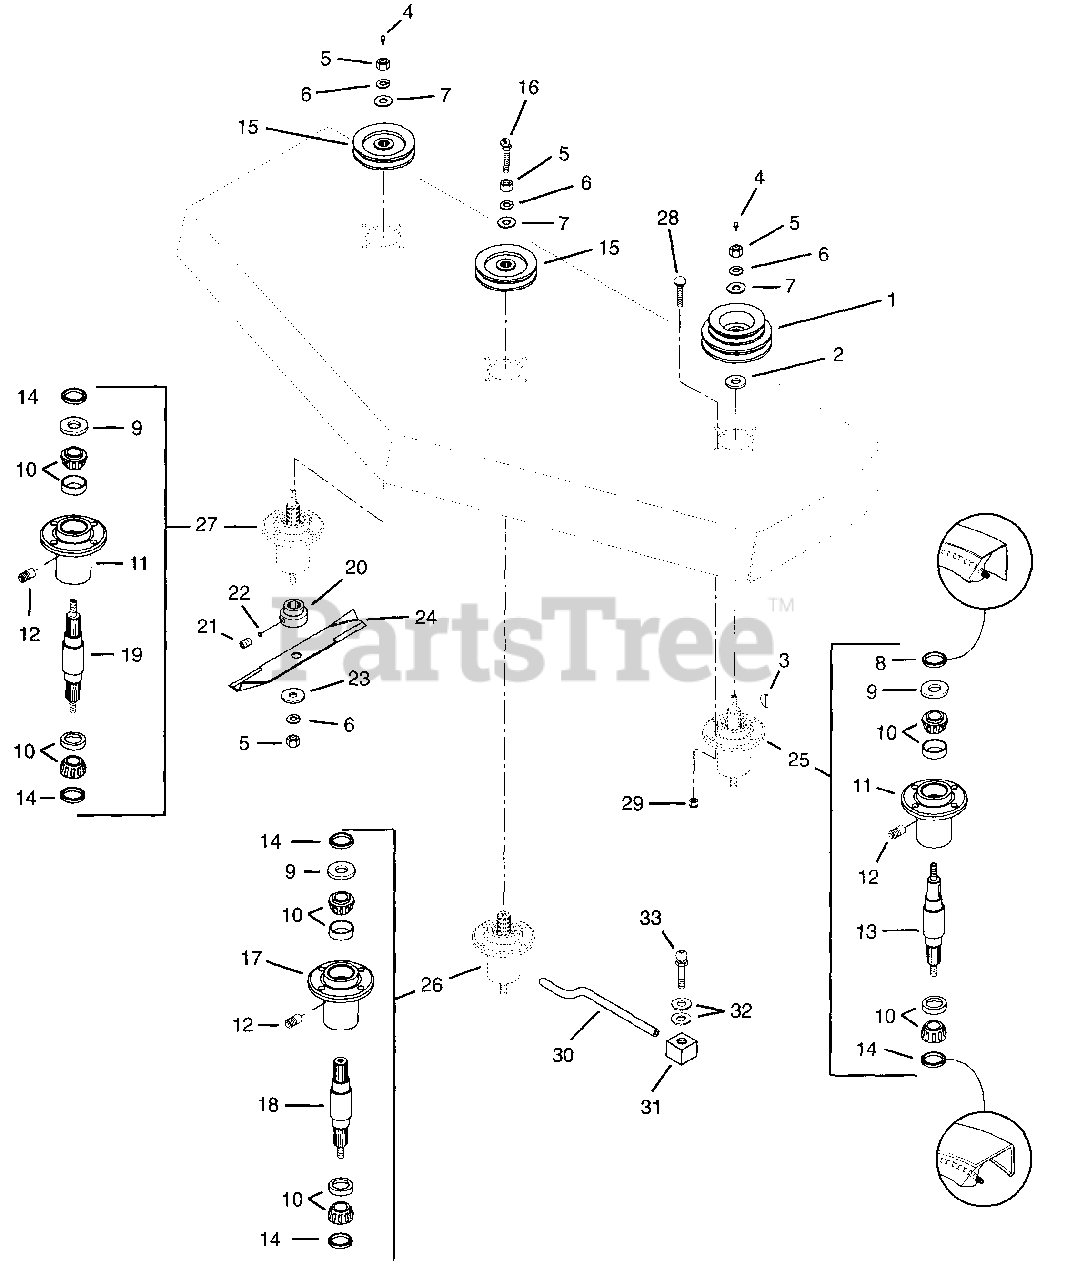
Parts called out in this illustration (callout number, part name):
2	Washer-Hardened-Thrust 1.00 x 1.55 x .03
3	Key-Woodruff .25 x 1.00 Hard #15
4	Fitting-Lube 1/8
5	Nut-Hex .625-11 Grade 2
6	Washer-Lock .625 x .156
7	Washer-Flat-Steel .687 x 1.312 x .150
8	Seal 1.987 x 1.500 x .313
9	Washer-Flat Steel 1.007 x 1.542 x .062
10	Assembly-Bearing Cup & Cone
11	Bearing Housing
12	Relief Fitting-Grease
13	Spindle Shaft Service Assembly
14	Seal 1.987 x 1.375 x .313
16	Bolt-Hex Spec 1/2-13 x 1.34
17	Bearing Housing
18	Spindle Shaft
19	Spindle Shaft Service Assembly
21	Screw-Set .25-20 x .25
23	Washer
24	Blade
25	Spindle Service Kit (Left)
26	Spindle Service Kit (Center)
27	Spindle Service Kit (Right)
28	Bolt-Round Head Square Neck .38-16 x 1.375
29	Nut-Locking-Nylon .375-16 Grade 2
30	Grease Tube
31	Grease Fitting
32	Washer-Flat-Steel .406 x .812 x .065
33	Fitting-Lube .12 x 65 x 1.18
